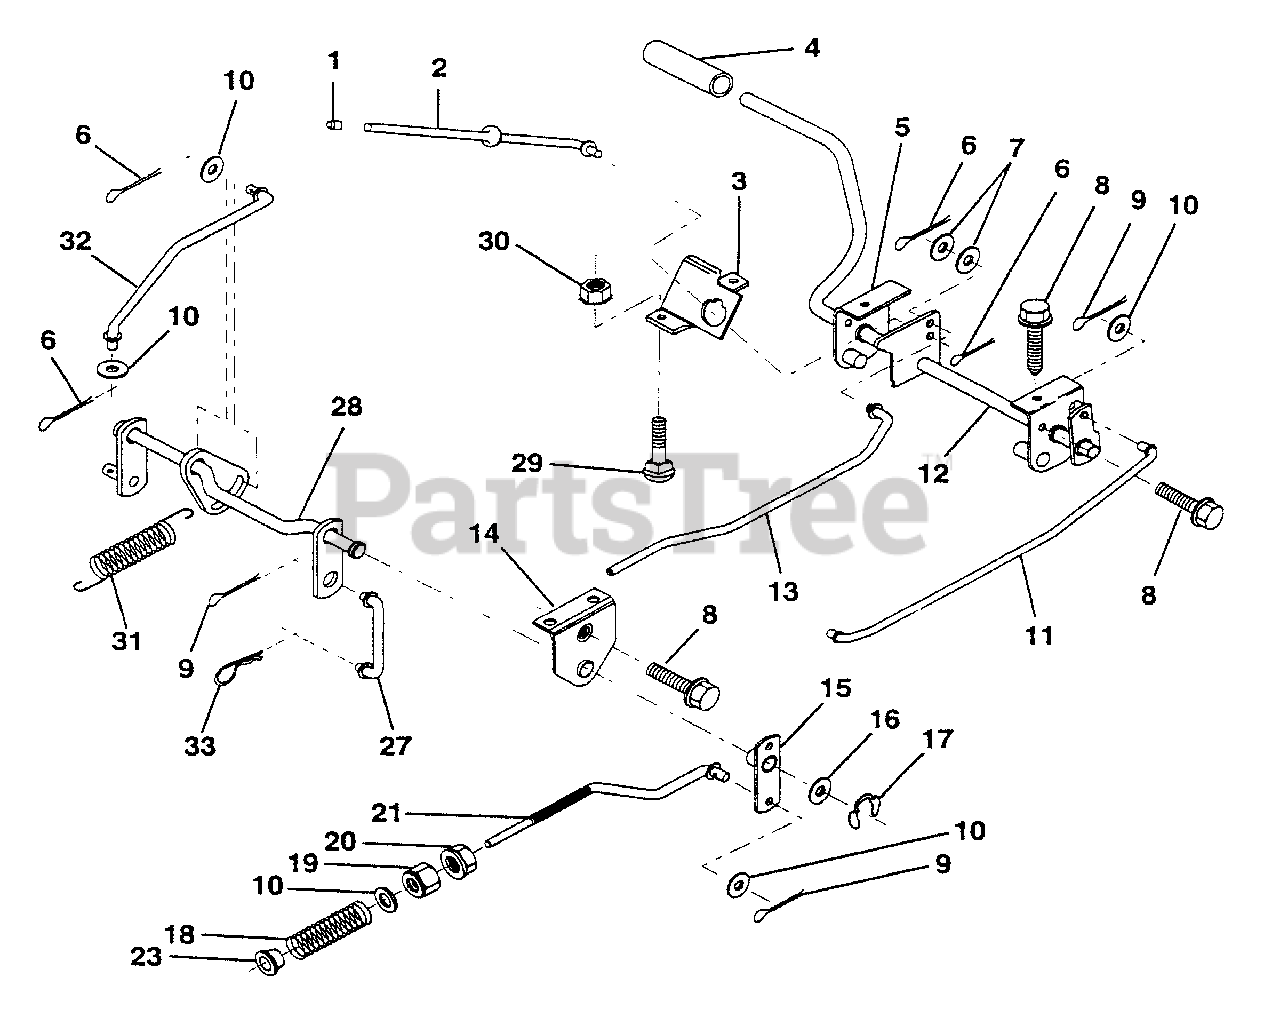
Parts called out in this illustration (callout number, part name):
1	Cap, Plunger
2	Rod, Parking Brake
3	Bracket, Parking Brake
4	Cover, Pedal
5	Bracket, Clutch/Brake Pedal, L.H.
6	Pin, Cotter 3/32 x 3/4
7	Washer 13/32 x 5/8 x 16 Gauge
8	Screw, Hex Head, Thd., Roll. 5/16-18 x 1/2
9	Pin, Cotter 1/8 x 3/4
10	Washer 13/32 x 13/16 x 16 Gauge
11	Rod, Brake, Front
12	Assembly, Clutch/Brake Pedal
13	Rod, Clutch
14	Bracket, Lift Shaft
15	Assembly, Brake, Pivot, Arm
16	Washer 25/32 x 1-1/8 x 16 Gauge
17	Ring, Klip
18	Spring, Brake Rod
19	Nut, Hex, Jam 3/8-16 UNC
20	Locknut, Hex, w/Wsh Ins 3/8-16 UNC
21	Rod, Brake, Rear
27	Link, Lift, Rear
28	Assembly, Rear Mower Lift
29	Bolt, Carriage 5/16-18 UNC x 3/4
30	Nut, Hex, Keps 5/16-16 UNC
31	Spring, Counterbalance
32	Link, Lift Lever
33	Retainer Spring
